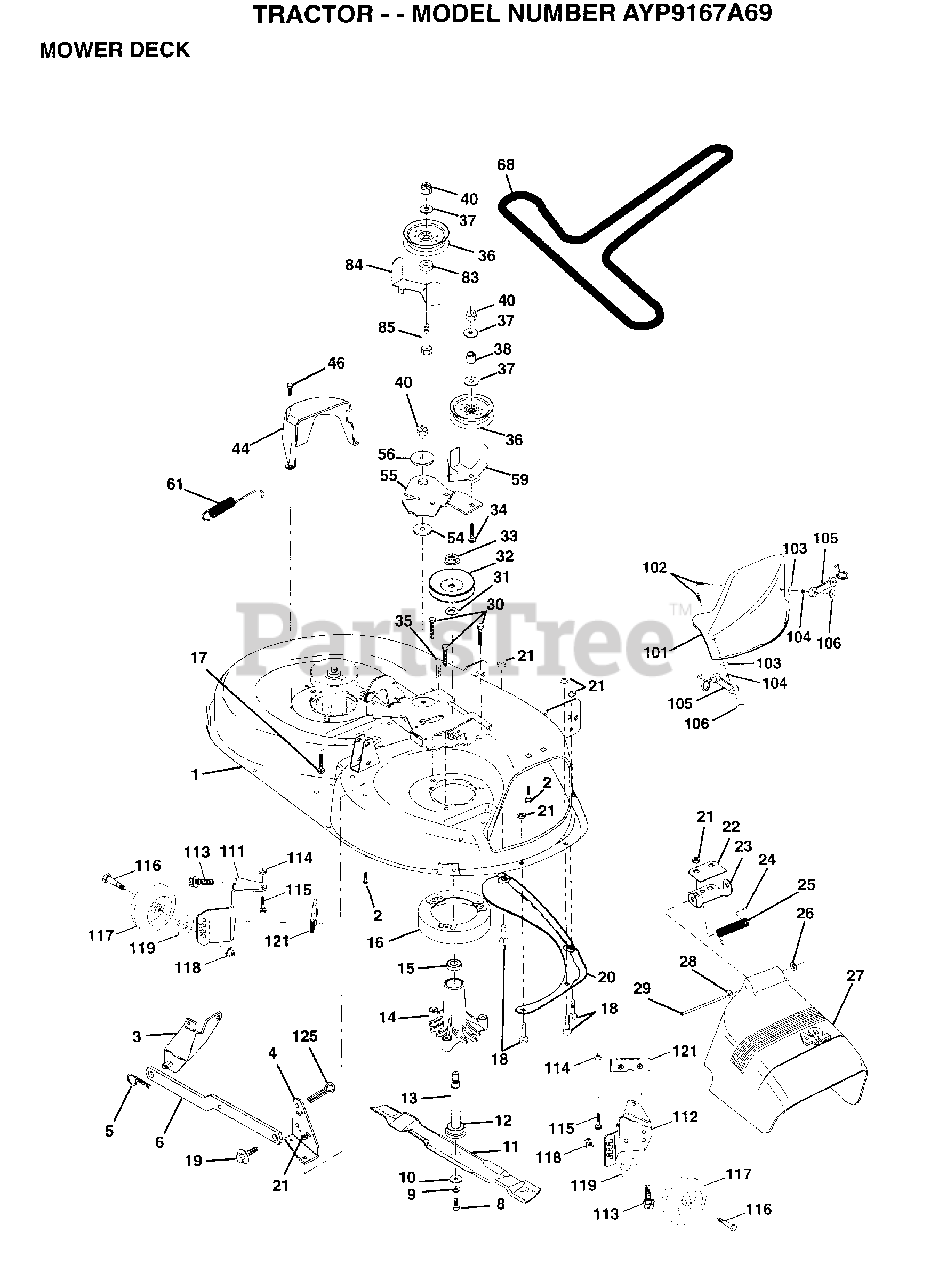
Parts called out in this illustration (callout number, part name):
1	DECK.WELD.42.
2	BOLT
3	BRKT ASM SWAY BAR
4	BRKT DECK SW BAR
8	BLADE BOLT
10	WASHER.HARD.BLADE
11	"BLADE.42"" MULCHER"
12	BEARING.BALL
14	HSG ASM MANDREL
15	BEARING
16	STRIPPER RND MWR
17	BOLT CARRIAGE
18	BOLT
19	BOLT SHD 5/16-18
22	STIFFENER BRKT
23	DEFLECTOR BRKT
24	CAP-SLEEVE LT
25	SPRING TORSION
26	NUT PUSH M
27	DEFLECTOR.SHIELD
28	WASHER
29	HINGE ROD
31	WASHER
34	BOLT
35	XMAS TREE FASTNER
36	FLAT IDLER PULLEY
37	WASHER
44	GUARD MAND LH BLK
46	SCREW.1/4-20X5/8
54	HARDENED WASHER
56	SPACER RETAINER
59	GUARD IDLER TUV
61	SPRING.EXTENSION
68	BELT.V.T-PATH
83	WASHER
85	BOLT RDHD 3/8-16
101	"COVER.MULCH.42"""
102	SCREW
103	WASHER #10
104	LOCKWASHER
106	WELDNUT
113	SCREW
116	BOLT.SHOULDER
117	WHEEL GAGE DONUT
118	LOCKNUT
119	WASHER
121	BRACKET.EXTRD.GWL
125	COTTER PIN
